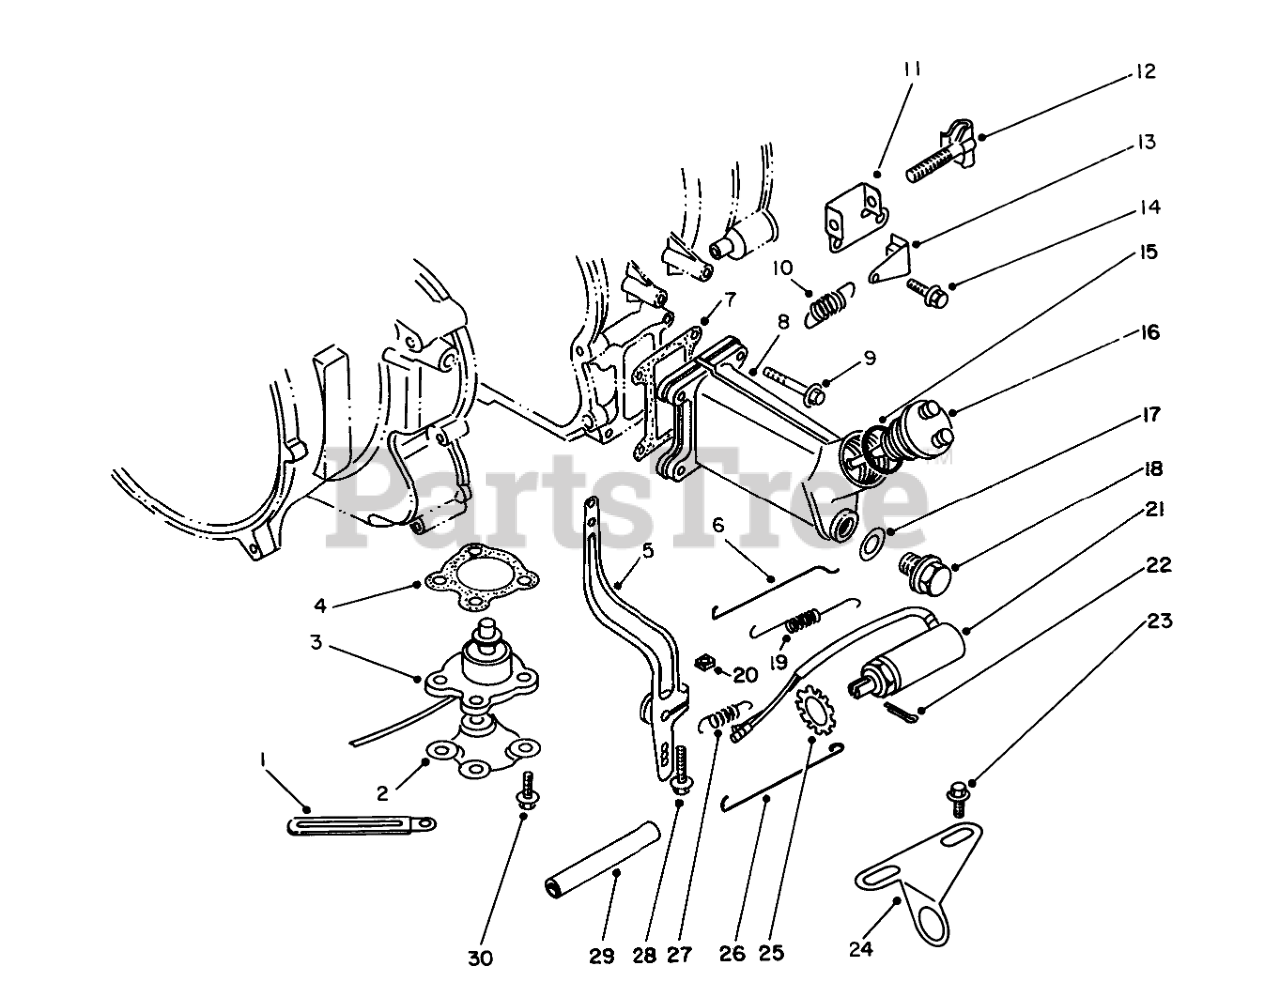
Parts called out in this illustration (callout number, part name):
1	Clamp
2	Plate
3	Oil Level Sensor
4	GASKET
5	Lever-Throttle Control
7	Gasket
8	Case-Oil Filler
10	Spring
11	Bracket
12	Bolt-Hook
15	O-RING
16	Oil Gauge
17	GASKET
19	Spring
21	Solenoid
24	Bracket
25	Lockwasher
27	SPRING
